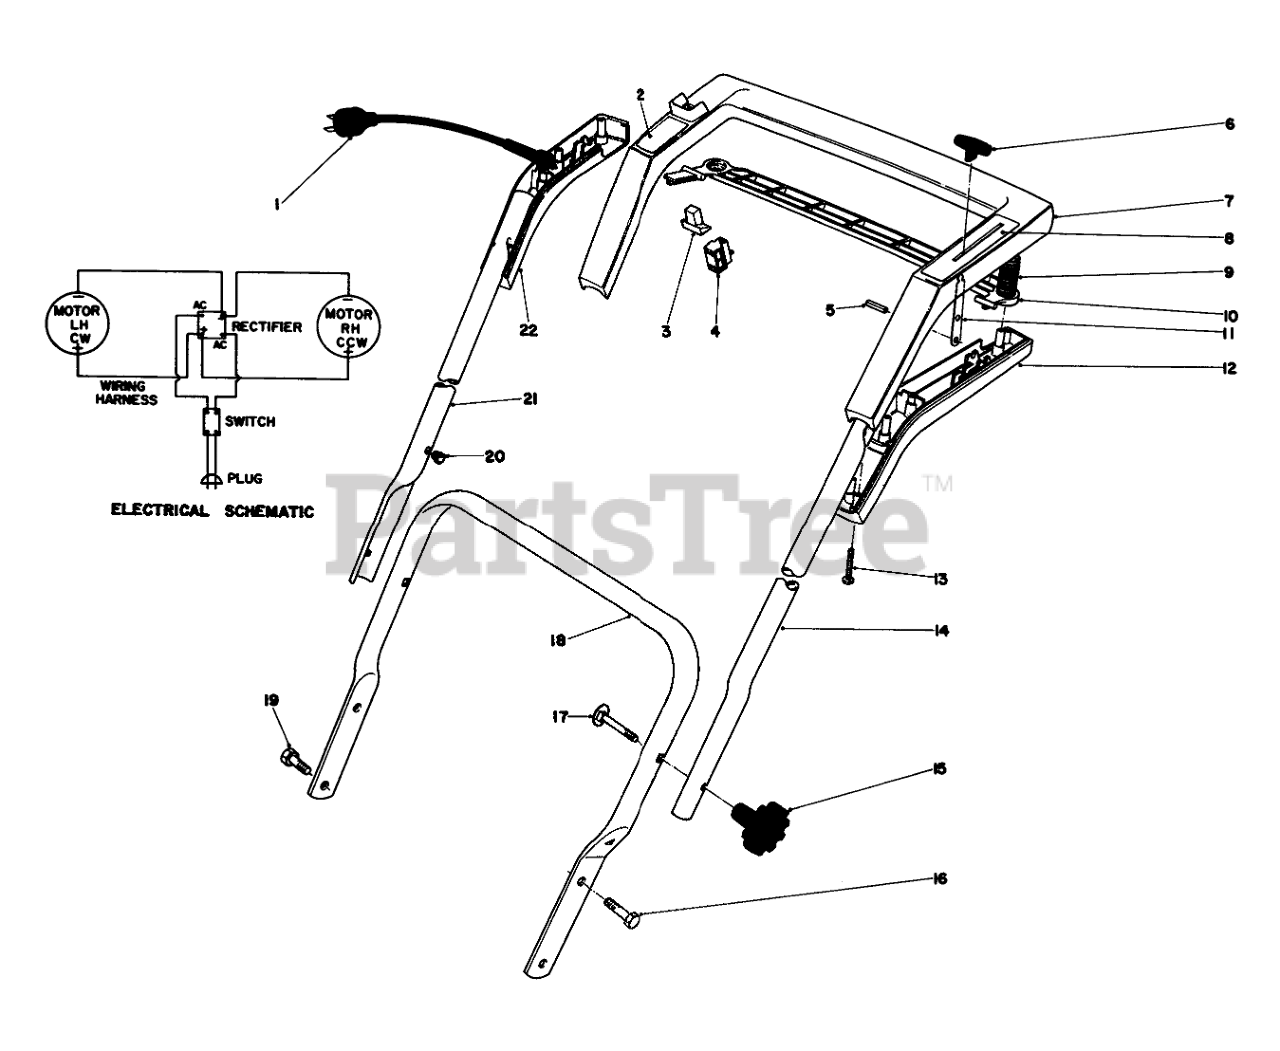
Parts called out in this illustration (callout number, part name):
1	Plug Pig Tail
2	Decal-On/Off
3	SWITCH BUTTON
4	Switch-On/Off
5	PIN-SPRING
6	CONTROL KNOB
7	Handle Grip
9	COMP SPRING
10	Squeeze Lever
11	Control Lever
12	Cover-Handle Grip L.H.
13	SCREW-PPH
14	Handle-Lower
16	SCREW-HH
17	SCREW-HANDLE
18	Handle-Lower
19	SCREW-HH
20	Bushing
21	Handle-Upper R.H.
22	Cover-Handle Grip R.H.
